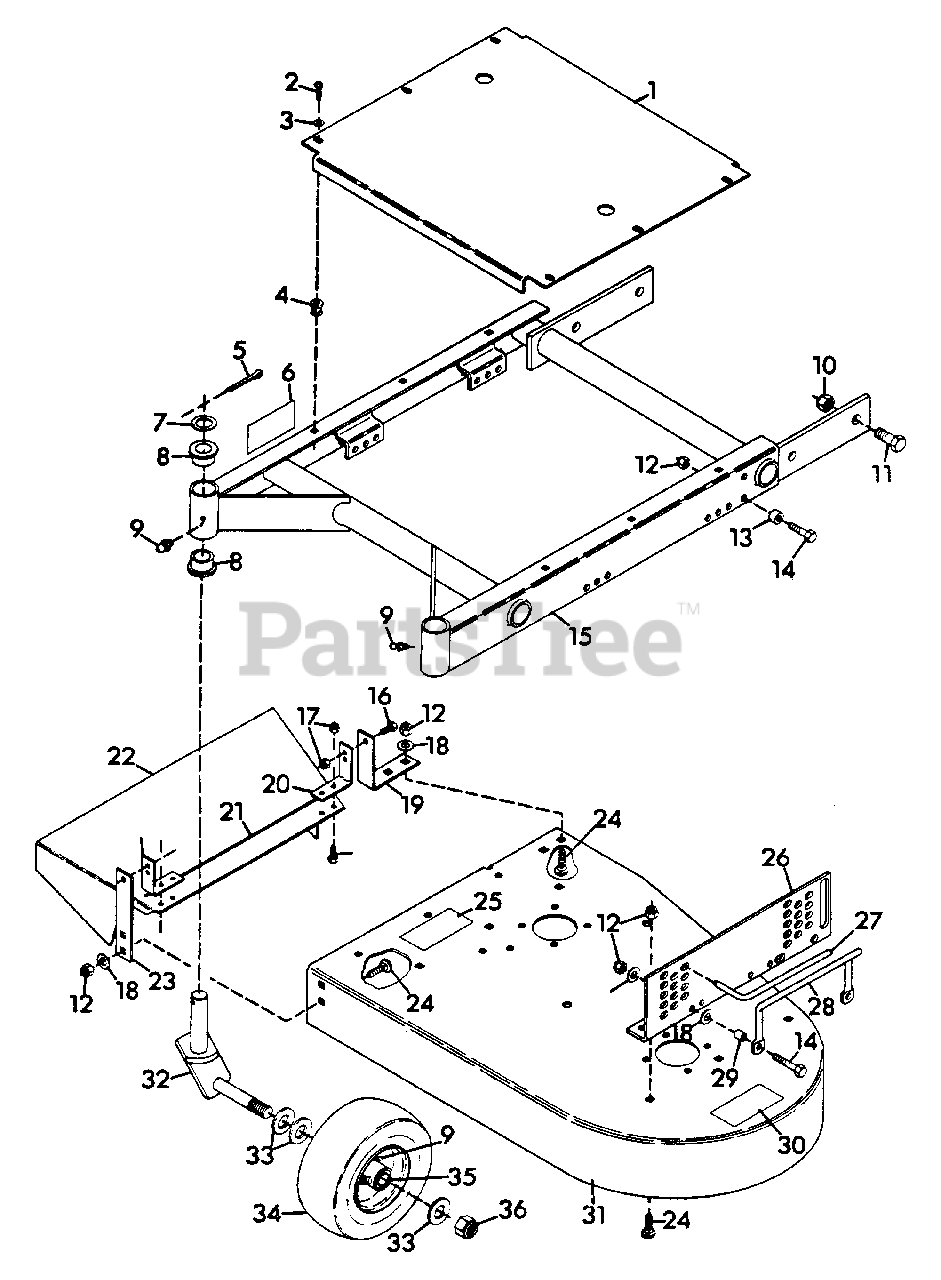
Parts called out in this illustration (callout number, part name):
1	Cover, Belt
2	Screw, Tapping 1/4-20x.625 P/Hd
3	Washer, Flat .281x.625x.065
4	Grommet, Plastic
5	Pin, Cotter .187x1.50
6	Decal, Danger Hand
7	Race, Bearing Thrust
8	Bushing, Pivot
9	Fitting, Lube 1/4-28
10	Nut, Lock 5/8-11
11	Bolt, Hex 5/8-11x1.50
12	Nut, Lock 3/8-16
13	Bushing .391x.622x.670
14	Bolt, Hex 3/8-16x1.50
15	Weldment, Frame
16	Bolt, Hex 5/16-18x.75
17	Nut, Lock 5/16-18
18	Washer, Flat .406x.812x.065
19	Bracket
20	Bracket
21	Stripe
22	Chute, Discharge
23	Bracket
24	Bolt, 3/8-16x1.00 Rd Hd Sq Nk
25	Decal, Warning Eye
26	Bracket, Mower Side Support L.H.
26	Bracket, Mower Side Support R.H.
27	Pin, Mower Locking
28	Handle
29	Bushing
30	Decal, Danger Foot
31	Weldment, 32" Pro Deck
32	Weldment, Caster Fork
33	Wheel, Gauge
34	Bearing, Gauge Wheel
35	Washer, Flat .812x1.496x.134
36	Nut, Lock 3/4-10
